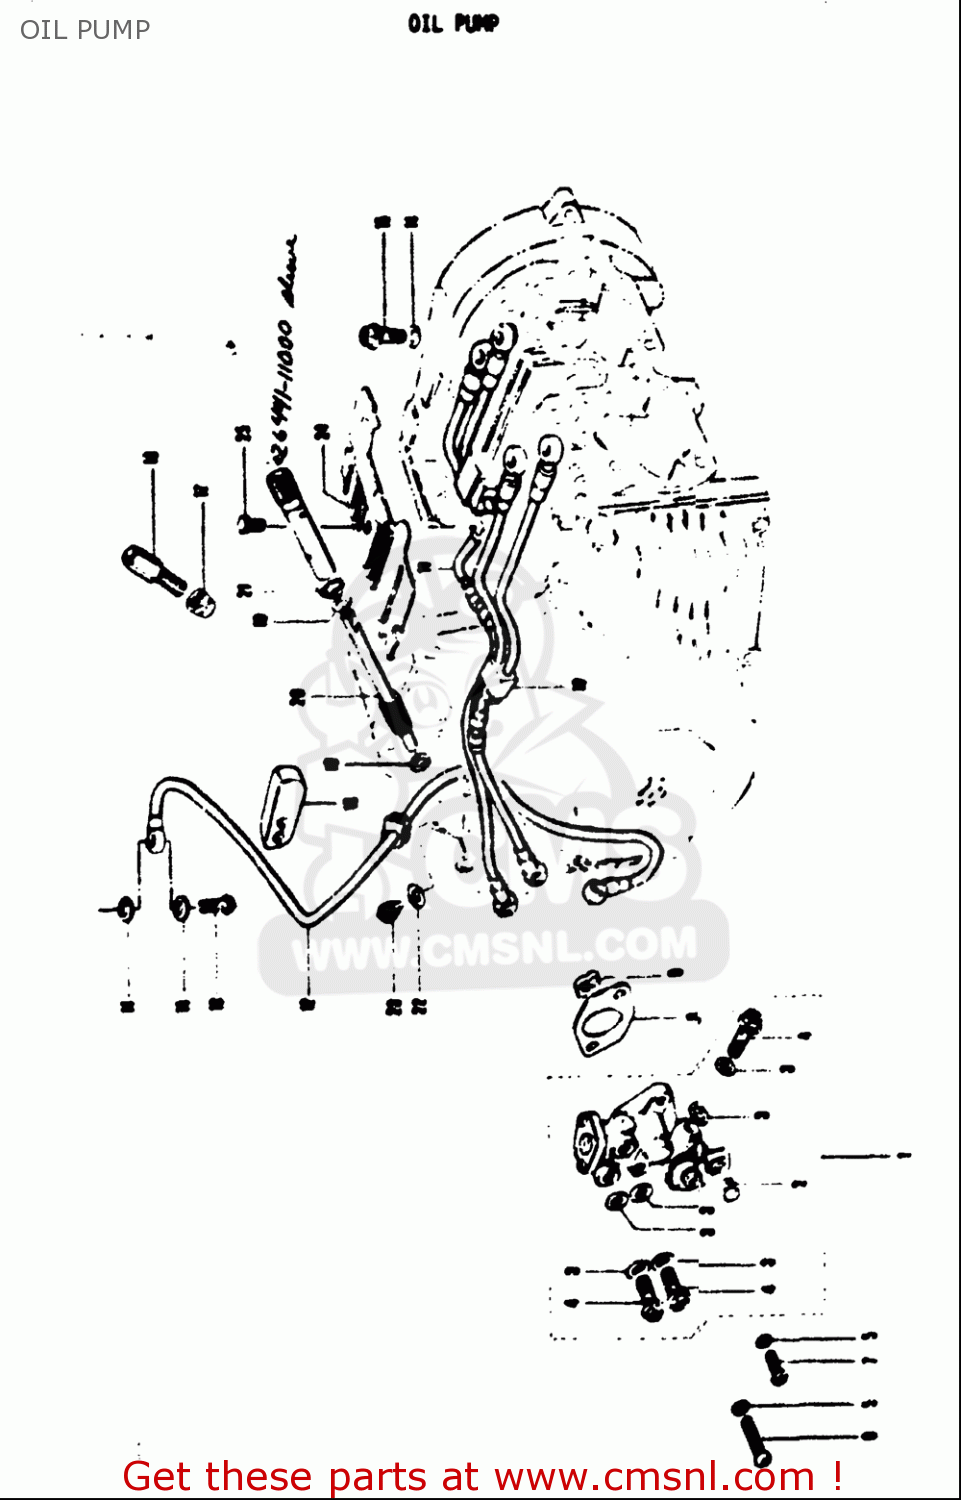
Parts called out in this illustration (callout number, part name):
2	TERMINAL,CABLE
3	GASKET(6.2X11X1).2 (NAS)
4	UNION BOLT
5	WASHER,LOCK
6	SCREW(5X27)
7	SCREW(5X14)
8	GASKET,OIL PUMP (NAS)
9	PIECE,OIL PUMP DRIVE
13	UNION BOLT
14	GASKET(6.2X11X1).2 (NAS)
15	UNION
19	WASHER(8X13.7X1)
21	O RING(D:1.3,ID:9.6)
22	WASHER
